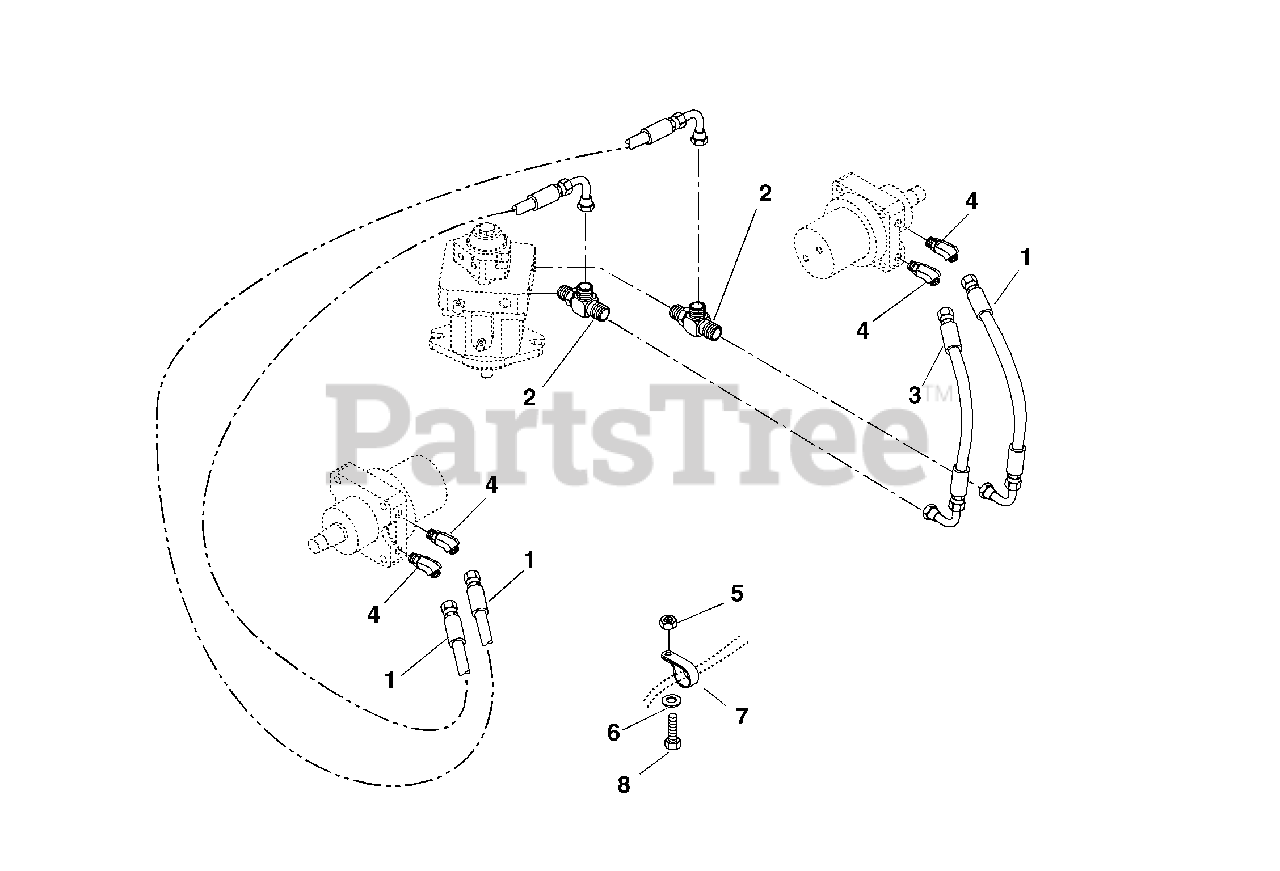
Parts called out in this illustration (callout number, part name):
1	Hose, Pump To Motor
2	Fitting, Hydraulic
3	Hose, Pump To Motor
4	Fitting, Hydraulic
5	Nut-Locking-Nylon .38-16
6	Washer-Flat-Steel .406 x .812 x .065
7	Clamp, Nylon
8	Bolt-Hex .38-16 x 1.00 Grade 5
